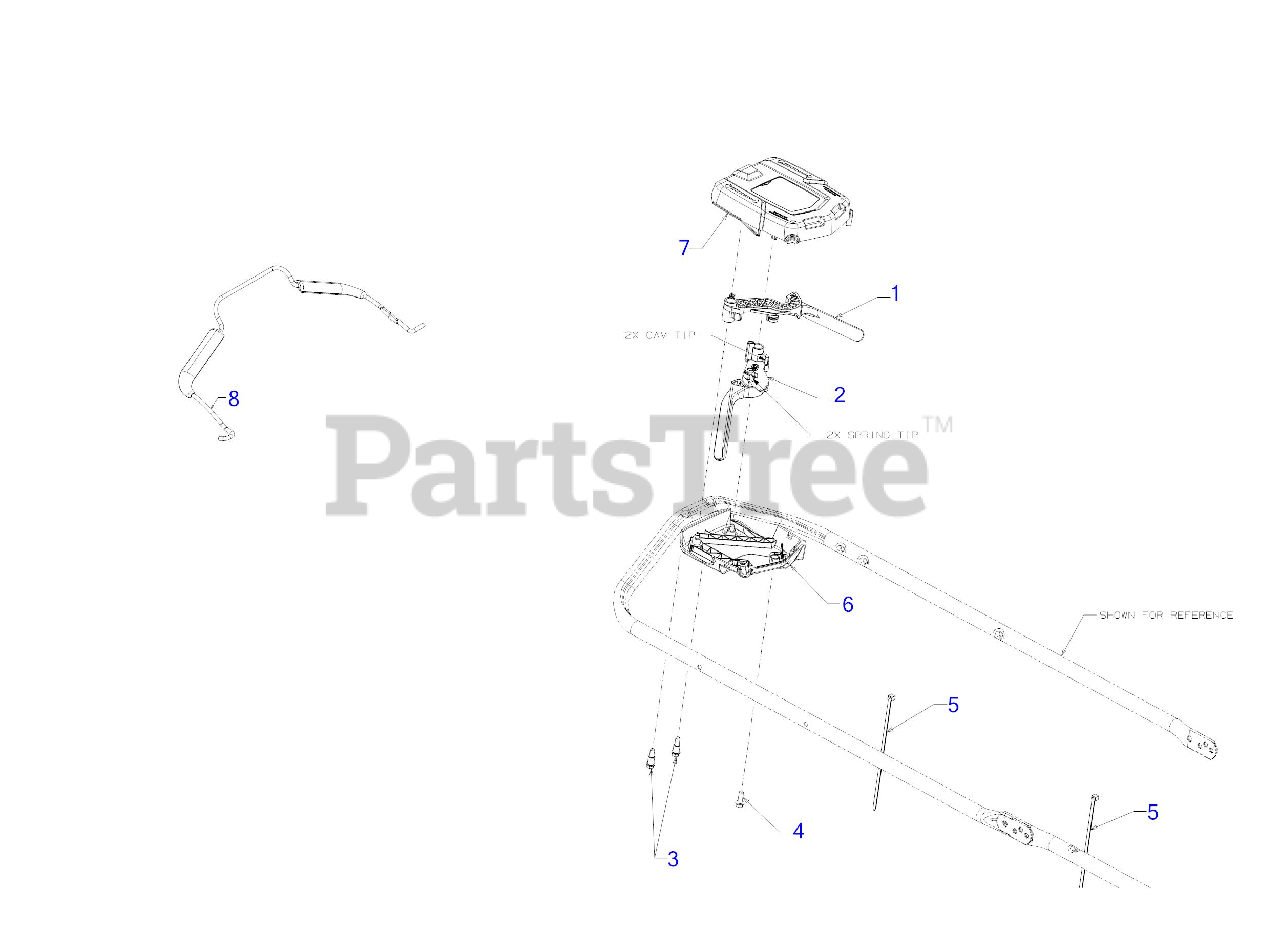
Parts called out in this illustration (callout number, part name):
1	CONTROL LEVER ASSEMBLY AWD LH RED
2	AWD CONTROL LEVER ASSEMBLY (RH) (RED)
3	SHOULDER SCREW 1/4-15 x .970
4	SCREW 1/4-15 x .750
5	7" CABLE TIE
6	LOWER CONTROL HOUSING
7	UPPER CONTROL HOUSING
8	AWD BAIL ASSEMBLY
